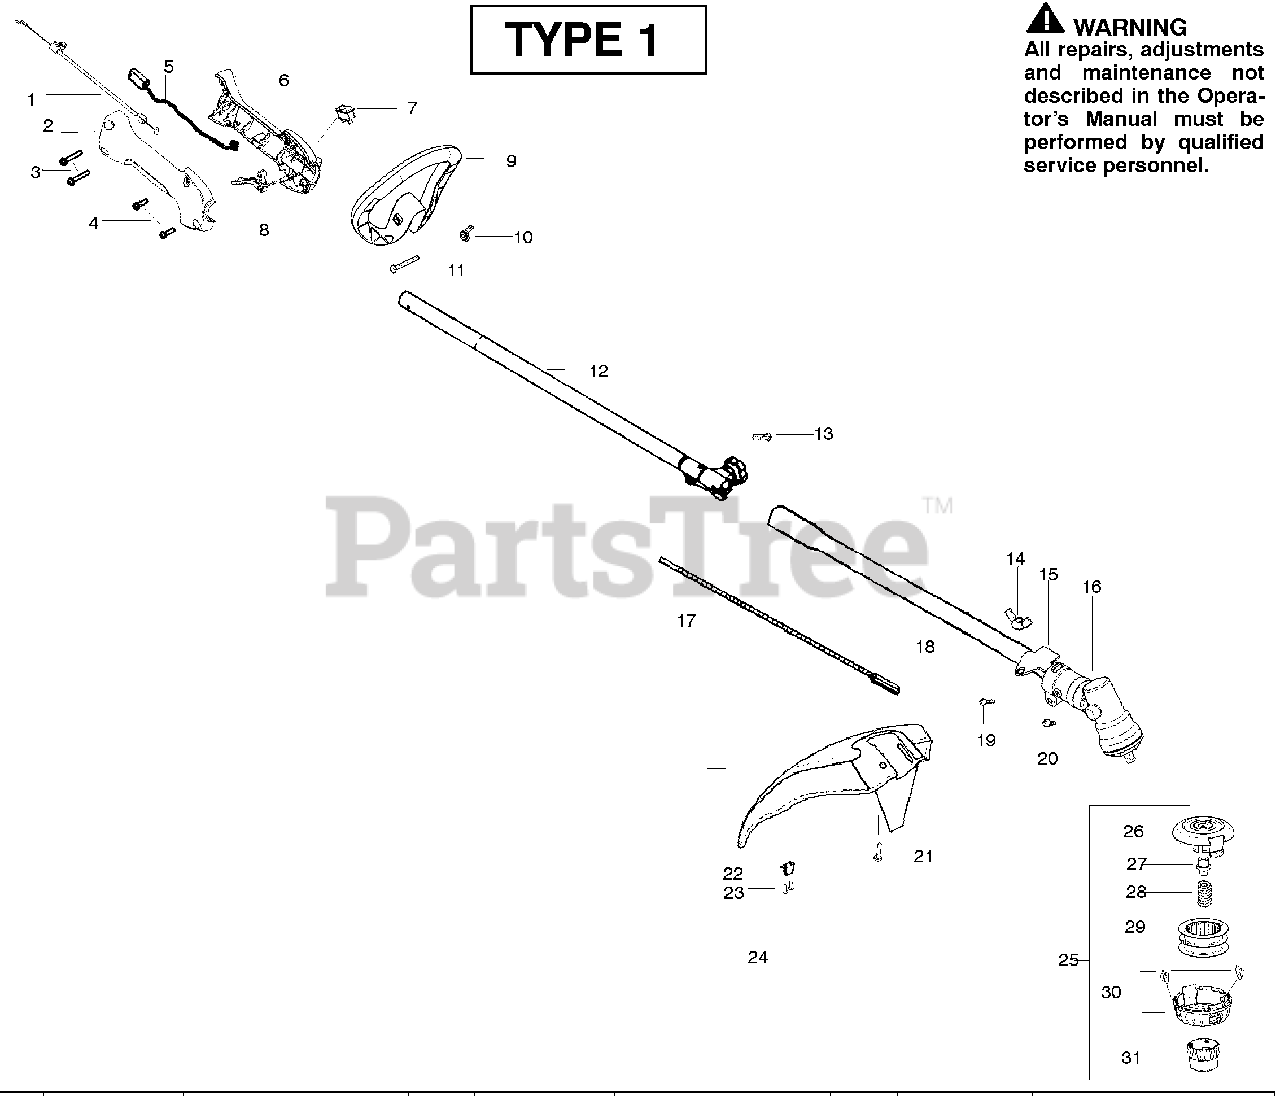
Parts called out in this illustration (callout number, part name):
1	Assy-Throttle Cable
2	Hsg.-Throttle (RH)
6	Hsg. Throttle (LH)
8	Trigger-Throttle
9	Handle-Assist
10	Wingnut
12	Kit-Upper Shaft
14	Wingnut
15	Bracket-Shield
17	Flexshaft-lower
18	Kit-Lower Shaft
24	Kit-Shield Assy.
25	Assy-TNG7
27	Adapter
28	Spring P25
29	Assy-Wound Spool
30	Kit-Cover and Eyelet
31	Knob P25
32	Operator Manual
33	Decal-Shaft Warning
34	Decal-Upper Shaft
